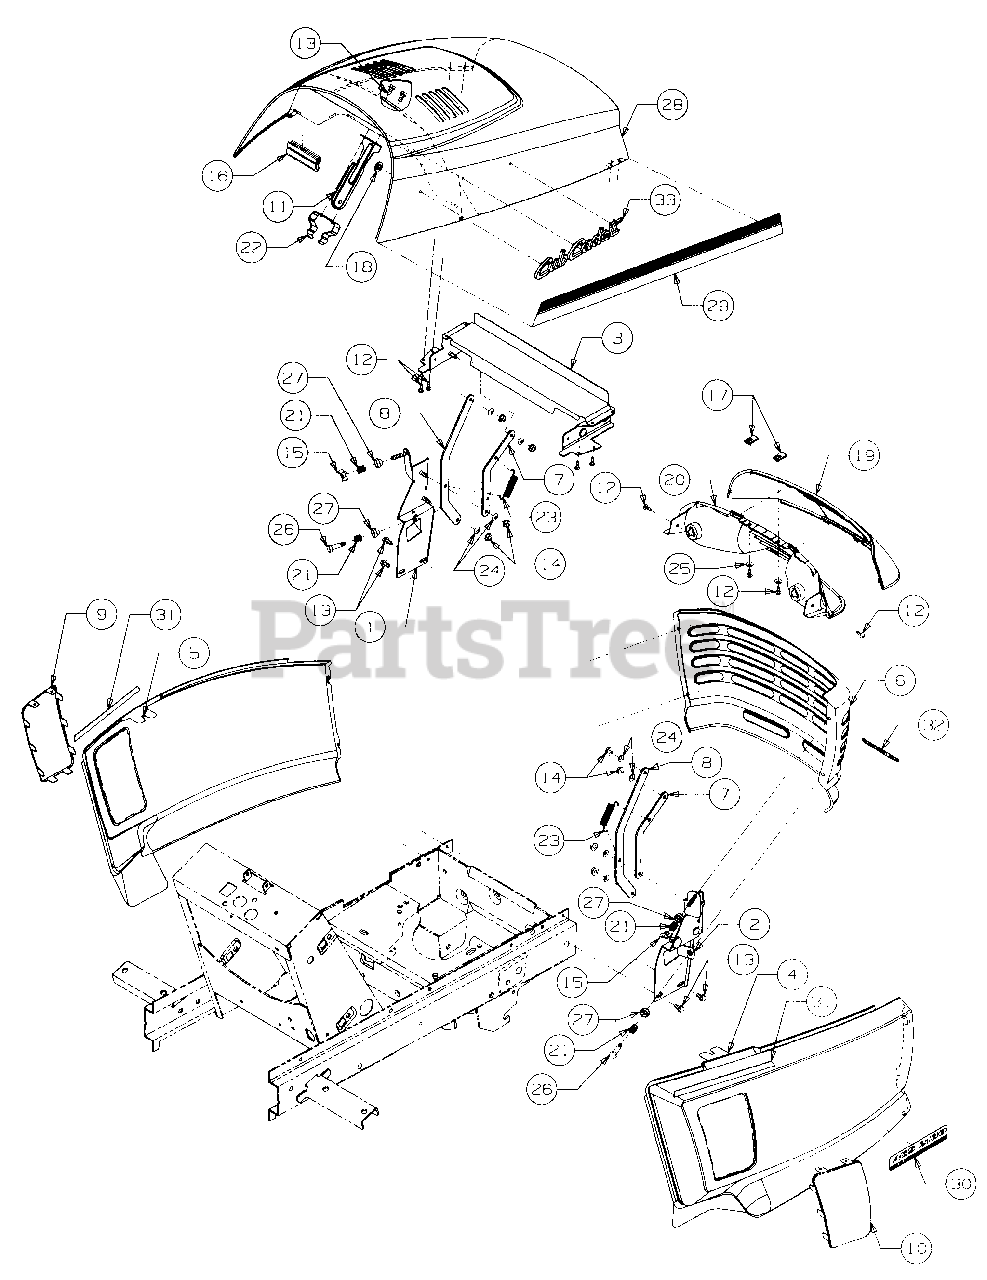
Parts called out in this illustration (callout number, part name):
1	Bracket, Grille LH
2	Bracket, Grille RH
8	Link, Long Hood
12	Screw, Truss Mach Tapp, #10 x .50 Lg
13	Screw, Hex Wash Tapp, 1/4 x .50 Lg
14	Nut, Hex Flange Lock, 1/4-20
15	Nut, Wing, 1/4-20
16	Seal, Heat Baffle
17	Nut, U-Type Speed, #10
18	Retainer, Push Nut
19	Lens, Cub Cadet
20	Reflector, Headlight
21	Spring, Compression, .50 OD x.50 Lg
22	Spring, Hood Latch
23	Spring, Extension, .50 OD x 2.25 Lg
24	Washer, Spring, .265 x .562 x .025 Thk
25	Washer, Flat, .218 x .62 x .063 Thk
26	Bolt, Shoulder, .31 Dia x .75 Lg
27	Bushing, Tapered
30	Graphic, AGS 2130
31	Strip, Protective
32	Graphic, Warning Hot
33	Script w/Studs, Cub Cadet
